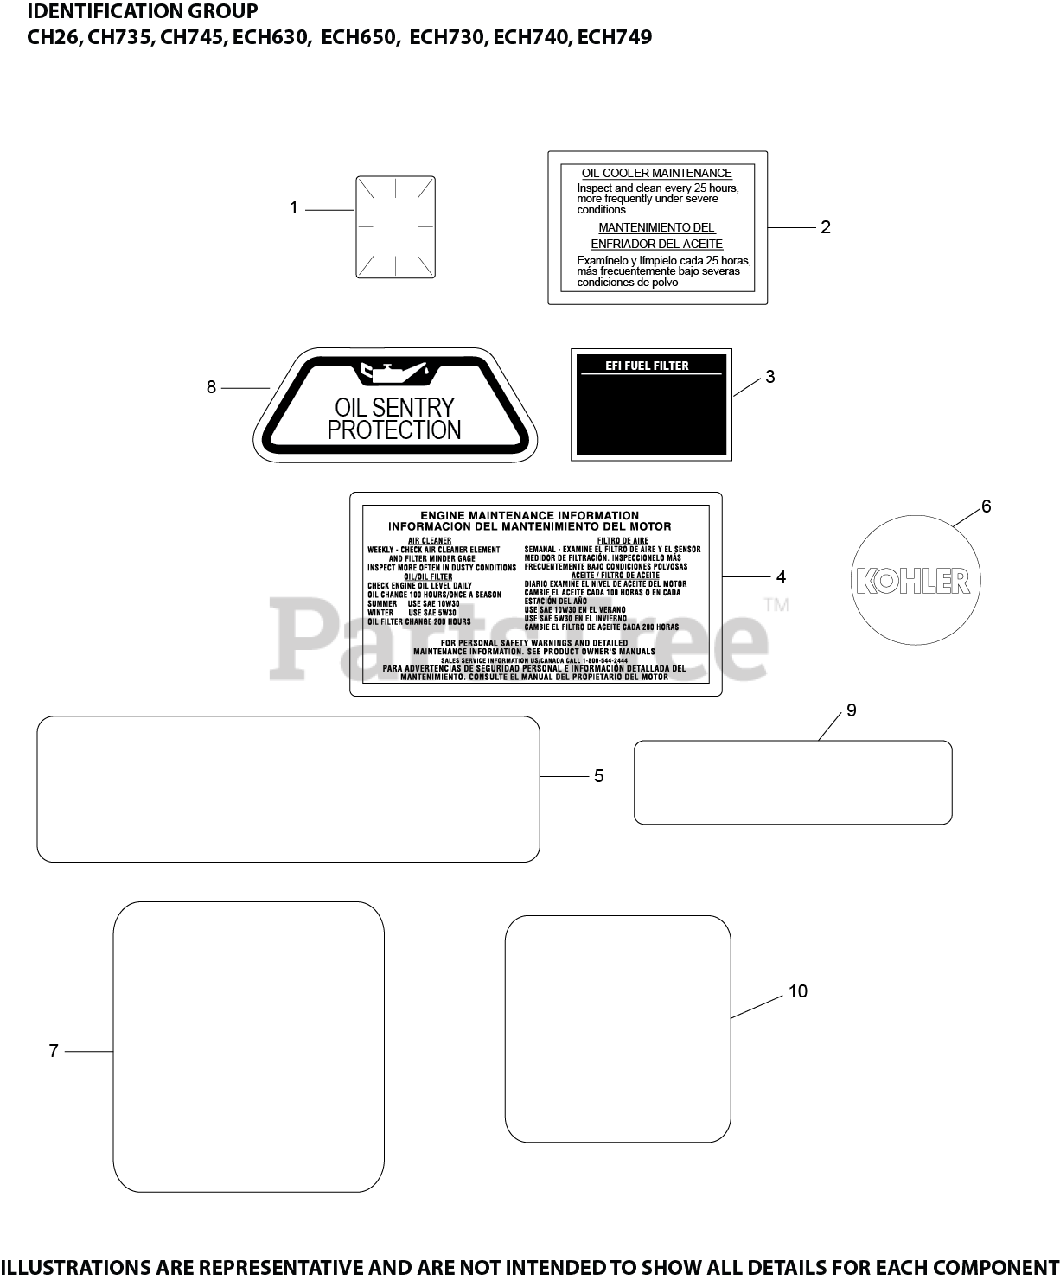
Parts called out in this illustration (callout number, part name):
1	LABEL, CLEAR LAMINATION - USE 25 113 79-S
3	LABEL, EFI FUEL FILTER
10	DECAL HDAC, 25 HP/747cc/ECV-ECH740
